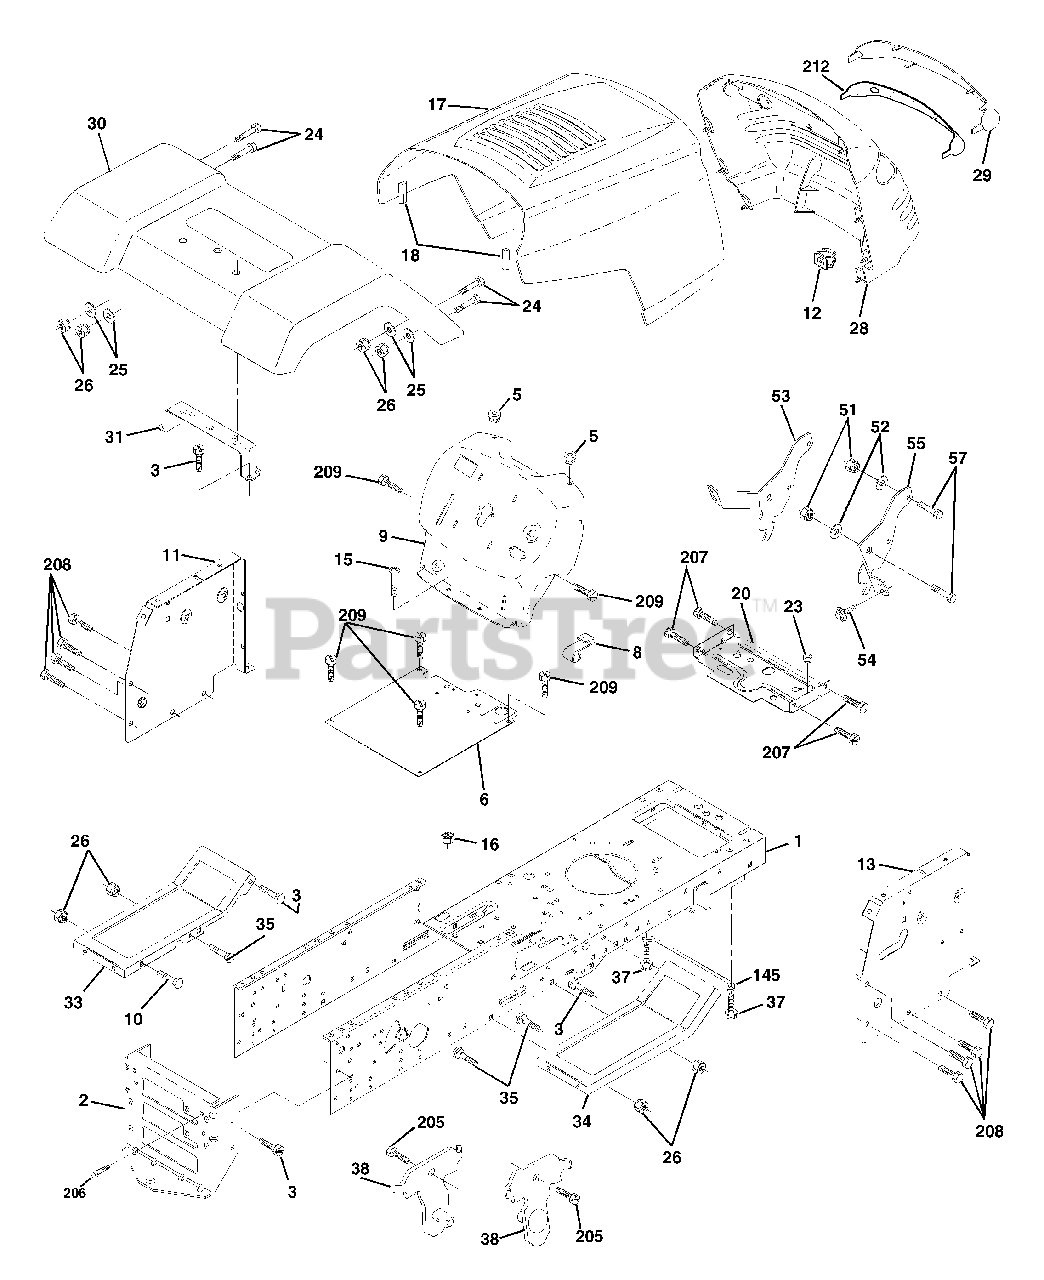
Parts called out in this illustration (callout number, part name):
1	Chassis
2	Drawbar
3	Screw 3/8-16 x 3/4
5	Bumper Hood/Dash
6	Saddle Flat Lt Fender Shift
8	Clip Retainer Slide-On
9	Dash
10	Bolt Rd Hd Sqnk. 3/8-16 Unc x 1
11	Panel Asm. Dash Lh
12	Clip Tinnerman Grile P/L
15	Screw Mach Trhd 5/16-18 Unc x 3/4
16	Nut Keps 5/16-18 Unc
17	Hood
18	Bumper Hood
20	Plate Mtg Battery/Fuel Tank Fr
23	Bushing Snap Nyl Blk Fuel Line
24	Bolt Fin Hex 3/8-16 Unc x 1 Gr. 5
25	Washer 13/32 x 13/16 x 12 Ga.
26	Nut Lock Hex w/Insert 3/8-16 UNC
28	Grill/Lens Asm
29	Lens Quadra
30	Fender Asm
31	Bracket Fender
33	Footrest Lh
34	Footrest Rh
35	Bolt Rd Hd Sht. Sqnk. 3/8-16 x 3/4
37	Screw Thdrol 5/16-18 x 1/2 Tyt
38	Bracket Asm. Pivot Mower Rear
51	Nut Lock Hex W/Ins. 1/4-20
52	Washer 9/32 x 7/8 x 16 Ga.
53	Bracket Grille LH
54	Screw Hex Wshd 8-18 x 7/8
55	Bracket, Grille RH
57	Bolt Fin Hex 1/4-20 x .75
145	Rod Pivot Chassis/Hood
205	Screw Thdrol 3/8-16 x 1/2
206	Bolt shoulder 5/16-18
207	Screw Thdrol 5/16-18 x 1/2
208	Screw Thdrol 3/8-16 x 1/2
209	Screw Hex Wsh Thdrol 3/8-16
212	Insert Lens Reflector
